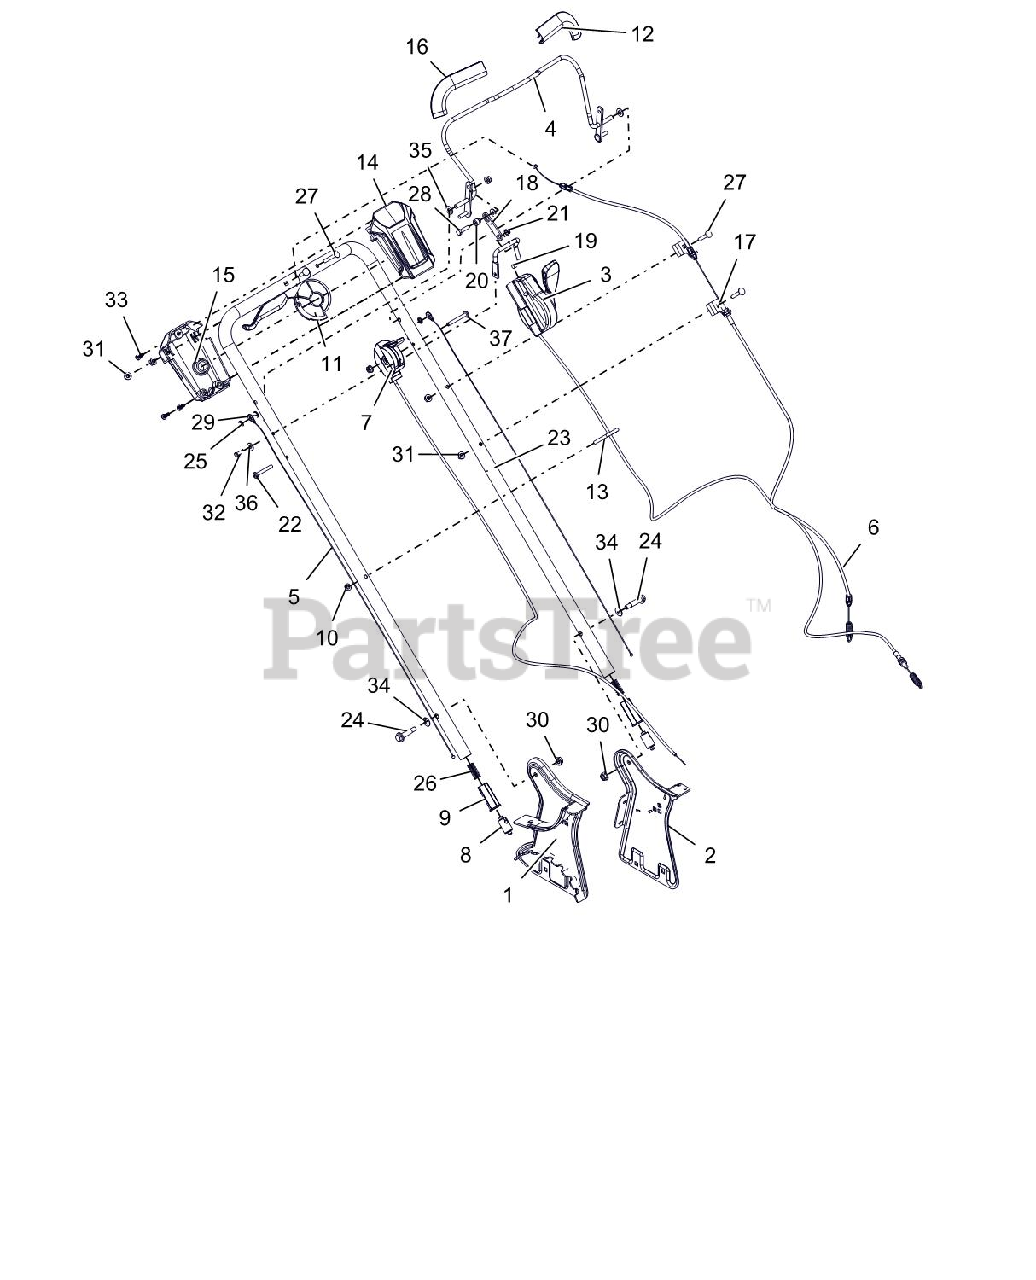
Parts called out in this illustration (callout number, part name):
1	SUPPORT, RH HANDLEBAR
2	SUPPORT, LH HANDLEBAR
3	ASSY, BBC CONTROL
4	WLDMT, OPC BAIL, BBC
5	CABLE, LM HANDLE ADJUST
6	CABLE, DRIVE CONTROL
7	CONTROL, THROTTLE
8	PLUNGER, HANDLEBAR LOCKING
9	INSERT, HANDLEBAR ADJUST
10	@NUT-LK-NYL-FLG .25-20 YWZC
11	HANDLE, DRIVE CONTROL
12	GUARD, FINGER - LH
13	HOLDER, RECOIL CORD
14	HOUSING, UPPER DRIVE CONTROL
15	HOUSING, LOWER DRIVE CONTROL
16	GUARD, FINGER - RH
17	BRKT, CABLE - DRIVE
18	COUPLER, BBC CONTROL
19	WIREFORM, BBC CONTROL
20	BSHG, BBC LATCH
21	BUSHING, NYLON, .31, SPLIT
22	SCR M6-1.0X45 DIN7985A PH YWZC
23	HANDLEBAR, LM
24	BLT-SHLDR, .50X1.15X.312-18GR5
25	NUT-PUSH .25X.50 O.D.
26	SPRING, COMPRESSION
27	@BLT-RDHDSQNK .25-20X1.50 G5YZ
28	@BLT-HEX .25-20X1.00 GR5 YWZC
29	RG-RTNG-EXT .250X.010
30	@NUT-LK-TOP-FLG .31-18 YWZC
31	@NUT-LK-TOP-FLG .25-20 YWZC
32	PIN, .25 X .75
33	SCR-TAP 12-14X.75PLSTITE @BLZC
34	WSHR,.385X.745X.030 STL YWZC
35	@WSHR-FL-STL.344X.688X.065YWZC
36	@WSHR-FL-STL.281X.62X.065 YWZC
37	SCR, .25-20X2.00 PH PAN YWZC
